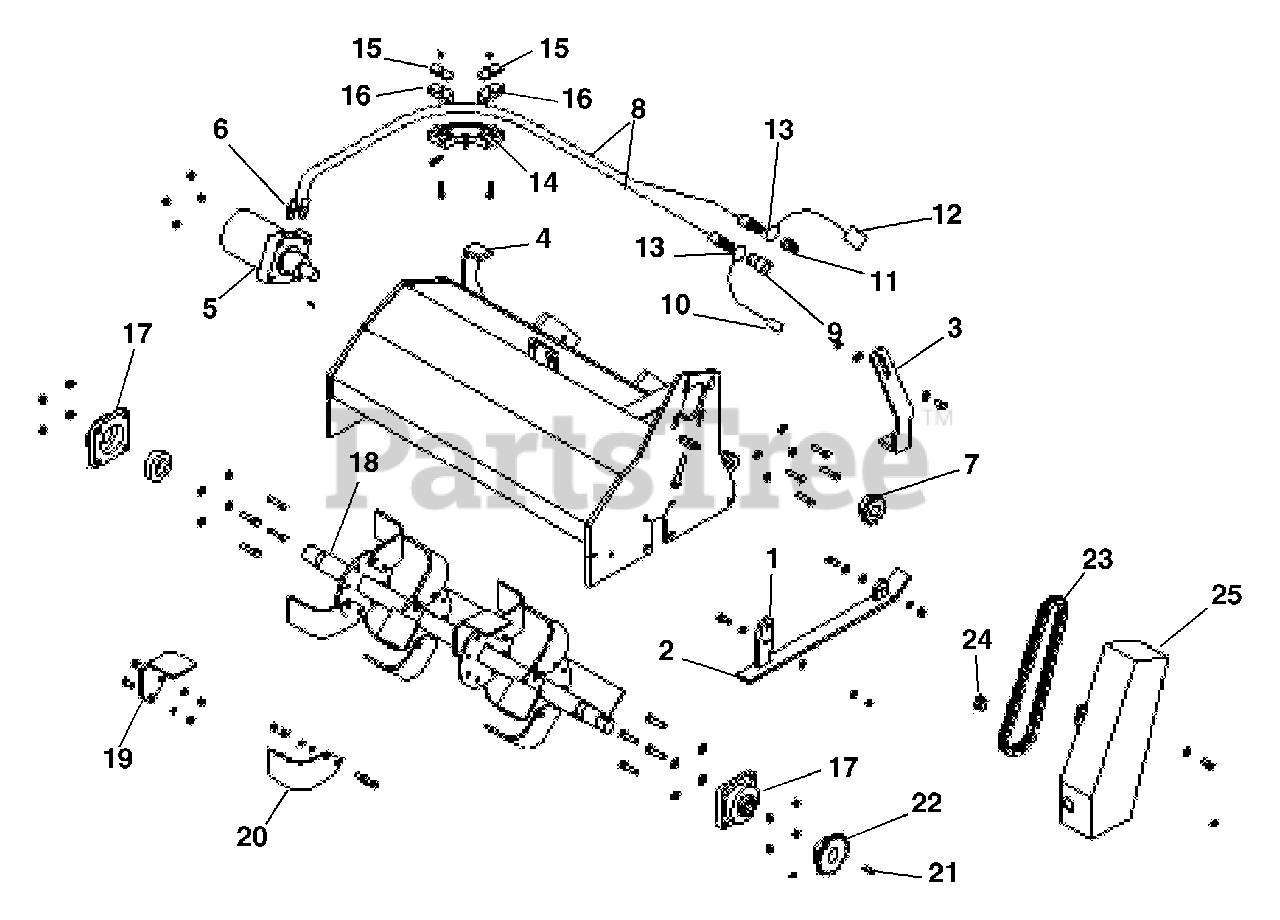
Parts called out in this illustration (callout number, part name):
1	ADJUSTER
2	SKID, LH
5	MOTOR, HYDRAULIC
6	FTG, HYD STR M8J-M10O
7	SPROCKET, 13T
8	HOSE, HYD .500-66-3K M8B0-F8J0
9	COUPLING, FML QCK .500-14 BSPP
10	PLUG, DUST .500
11	COUPLER, MALE QCK .500-14 BSPP
12	CAP, DUST .500
13	SEAL, BONDED
14	BRACKET,ATTACHMENT HOSE -ASSY
15	PLATE, COVER (CPT-3)
16	CLAMP, HOSE
17	BRG, SQ FLNG CARTRIDGE 45MM
18	SHAFT, TINE
19	TINE, RH
20	TINE, LH
21	KEY, 12MM X 8MM
22	SPROCKET, 19T
23	CHAIN, 60 ROLLER
24	LINK, MASTER JOIN
25	GUARD, CHAIN
